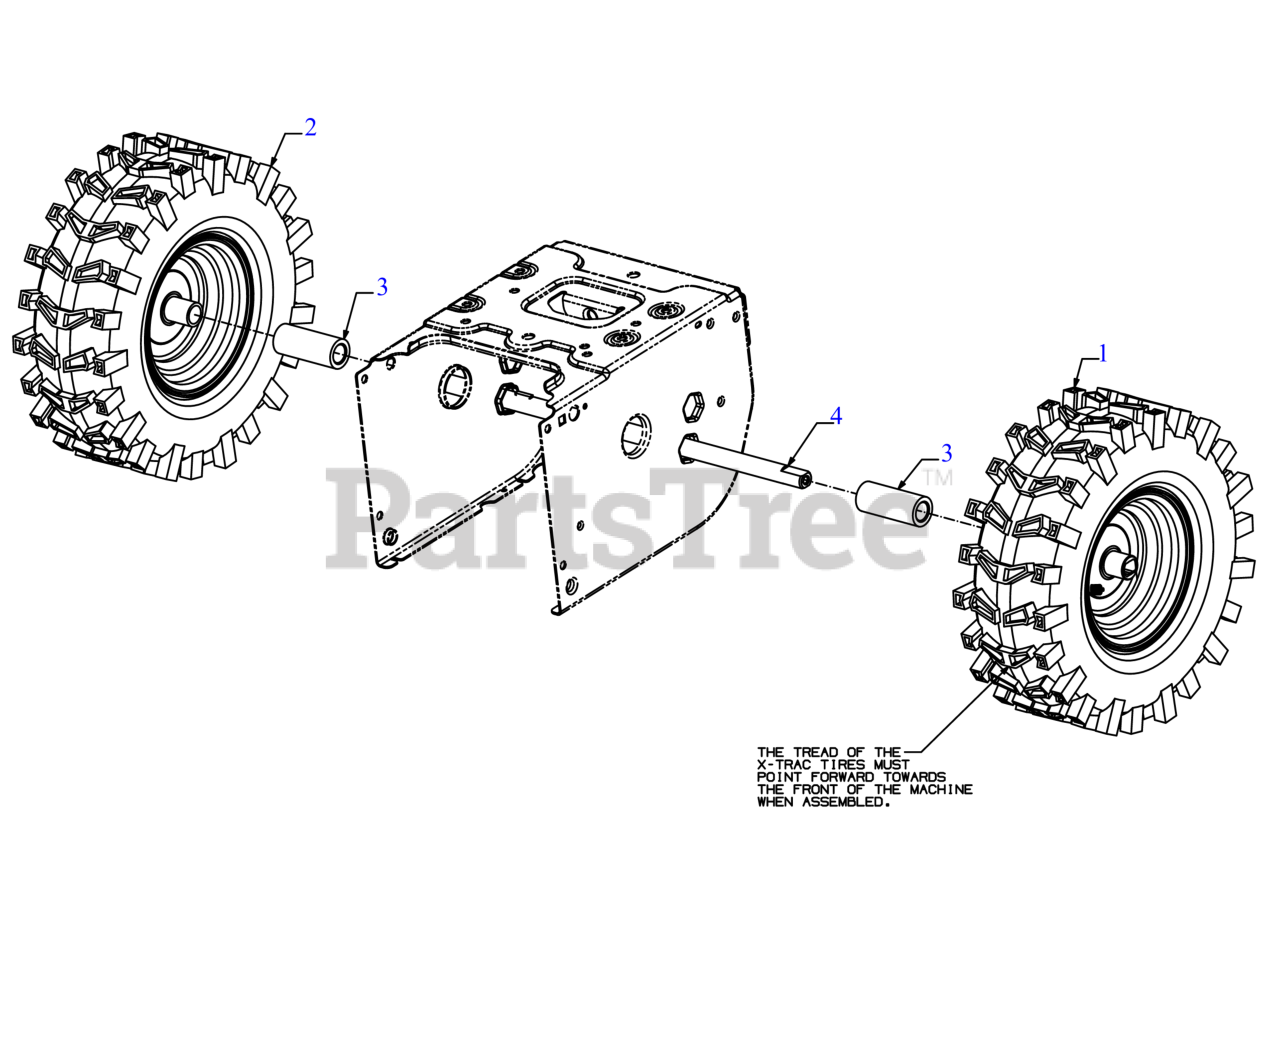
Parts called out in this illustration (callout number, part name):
1	COMPLETE WHEEL (13x5x6) (X-TRAC) (LH)
2	COMPLETE WHEEL (13x5x6) (X-TRAC) (RH)
3	WHEEL SPACER 1.25ODX.75X3.00
4	AXLE .75 x 22"
